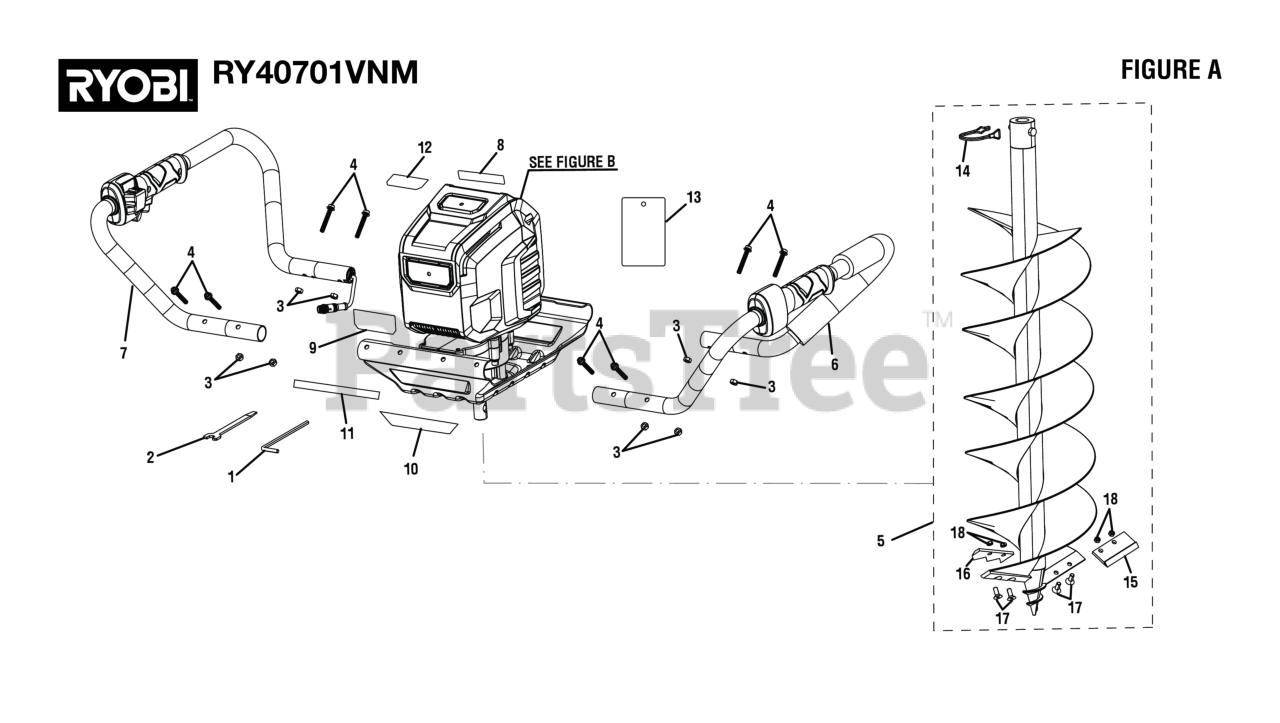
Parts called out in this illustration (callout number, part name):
1	Hexagon Key
3	Hex Nut (M6.3 x 1)
4	Screw (M6, Hex Hd.)
5	Auger
6	Handlebar Assembly (Left)
7	Handlebar Assembly (Right)
8	LED Label
9	RYOBI Logo Label
10	Data Label
11	Icon Label
12	Brushless Logo Label
13	Instruction Hang Tag
14	Safety Clip
15	Flat Blade Tip
16	Serrated Tip
18	Hex Nut (M5)
